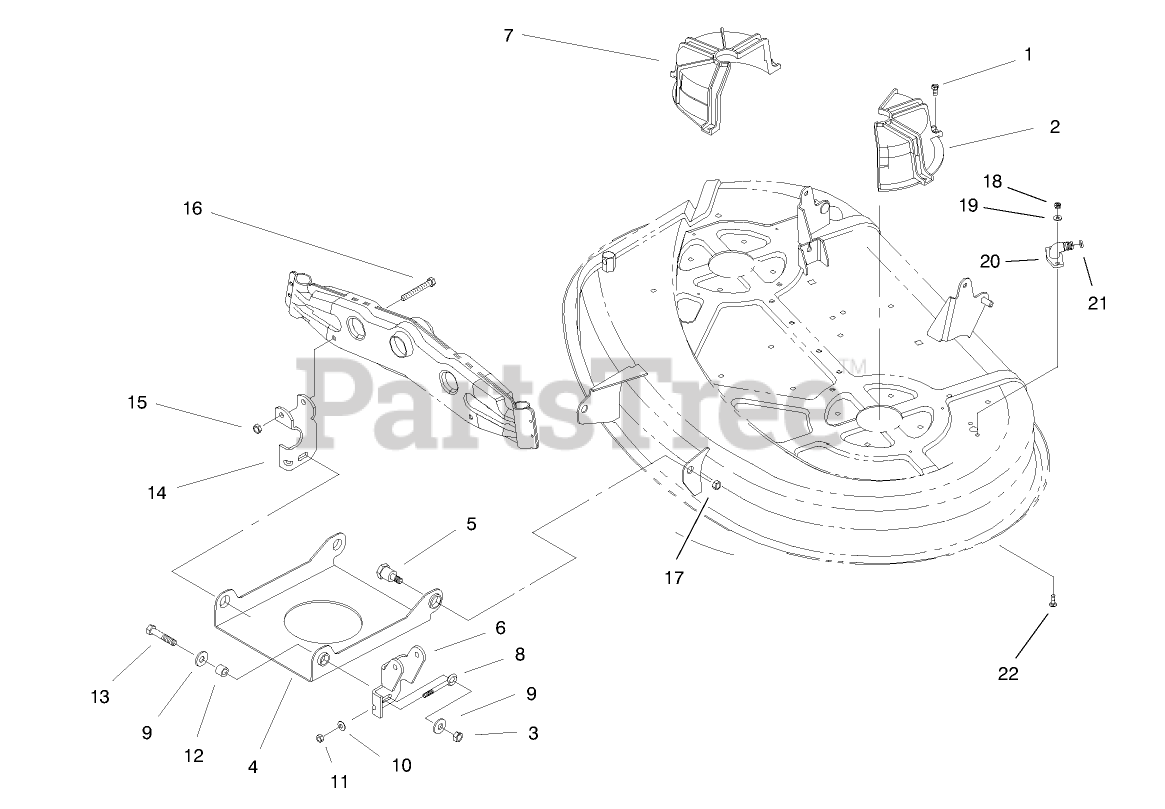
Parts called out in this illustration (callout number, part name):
1	SCREW-HWHTF
2	GUIDE-BELT, LH
3	NUT-LOCK, NI
4	PAN-DECK SUSPENSION, FRONT
6	BRACKET-SUSPENSION, LH
7	GUIDE-BELT, RH
8	SCREW-ADJUSTING
9	WASHER-HARDENED
10	WASHER-FLAT
11	NUT-LOCK, NI
12	SPACER
13	SCREW-HH
14	BRACKET-SUSPENSION, RH
15	NUT-LOCK, NI
16	SCREW-HH
17	NUT-LOCK, NI
18	NUT-LOCK, NI
19	WASHER-FLAT
21	O-RING
22	BOLT-CARR
